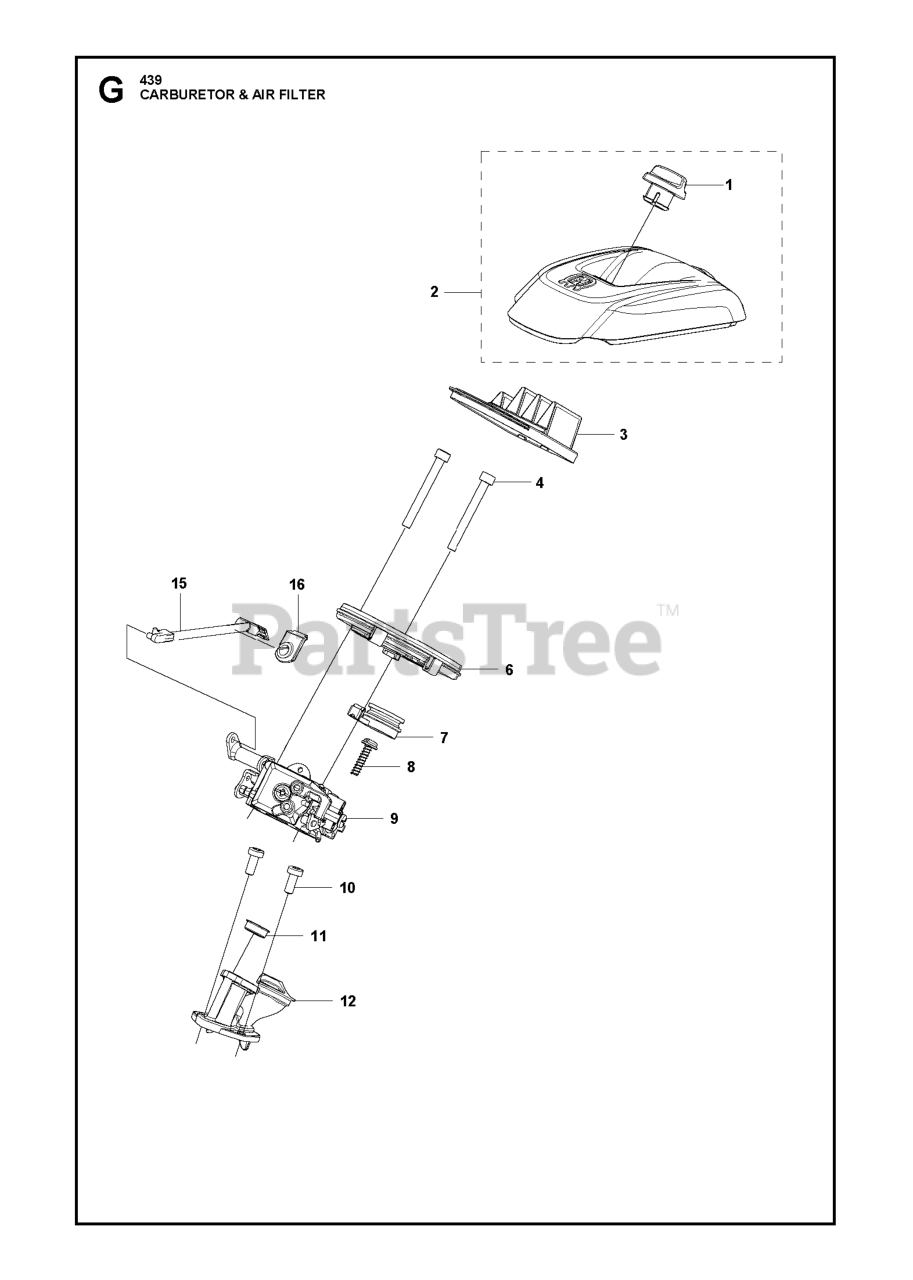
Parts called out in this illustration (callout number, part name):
2	AIR FILTER COVER ASSY 439
3	AIR FILTER 439/GZ3500L
6	AIR FILTER BOTTOM BOTTOM 436/G
7	SEAL RPLS 848CE083G2
9	CARBURETTOR 439
12	INLET PIPE
15	CHOKE ROD 439
16	GROMMET CHOKE 436_ORANGE
